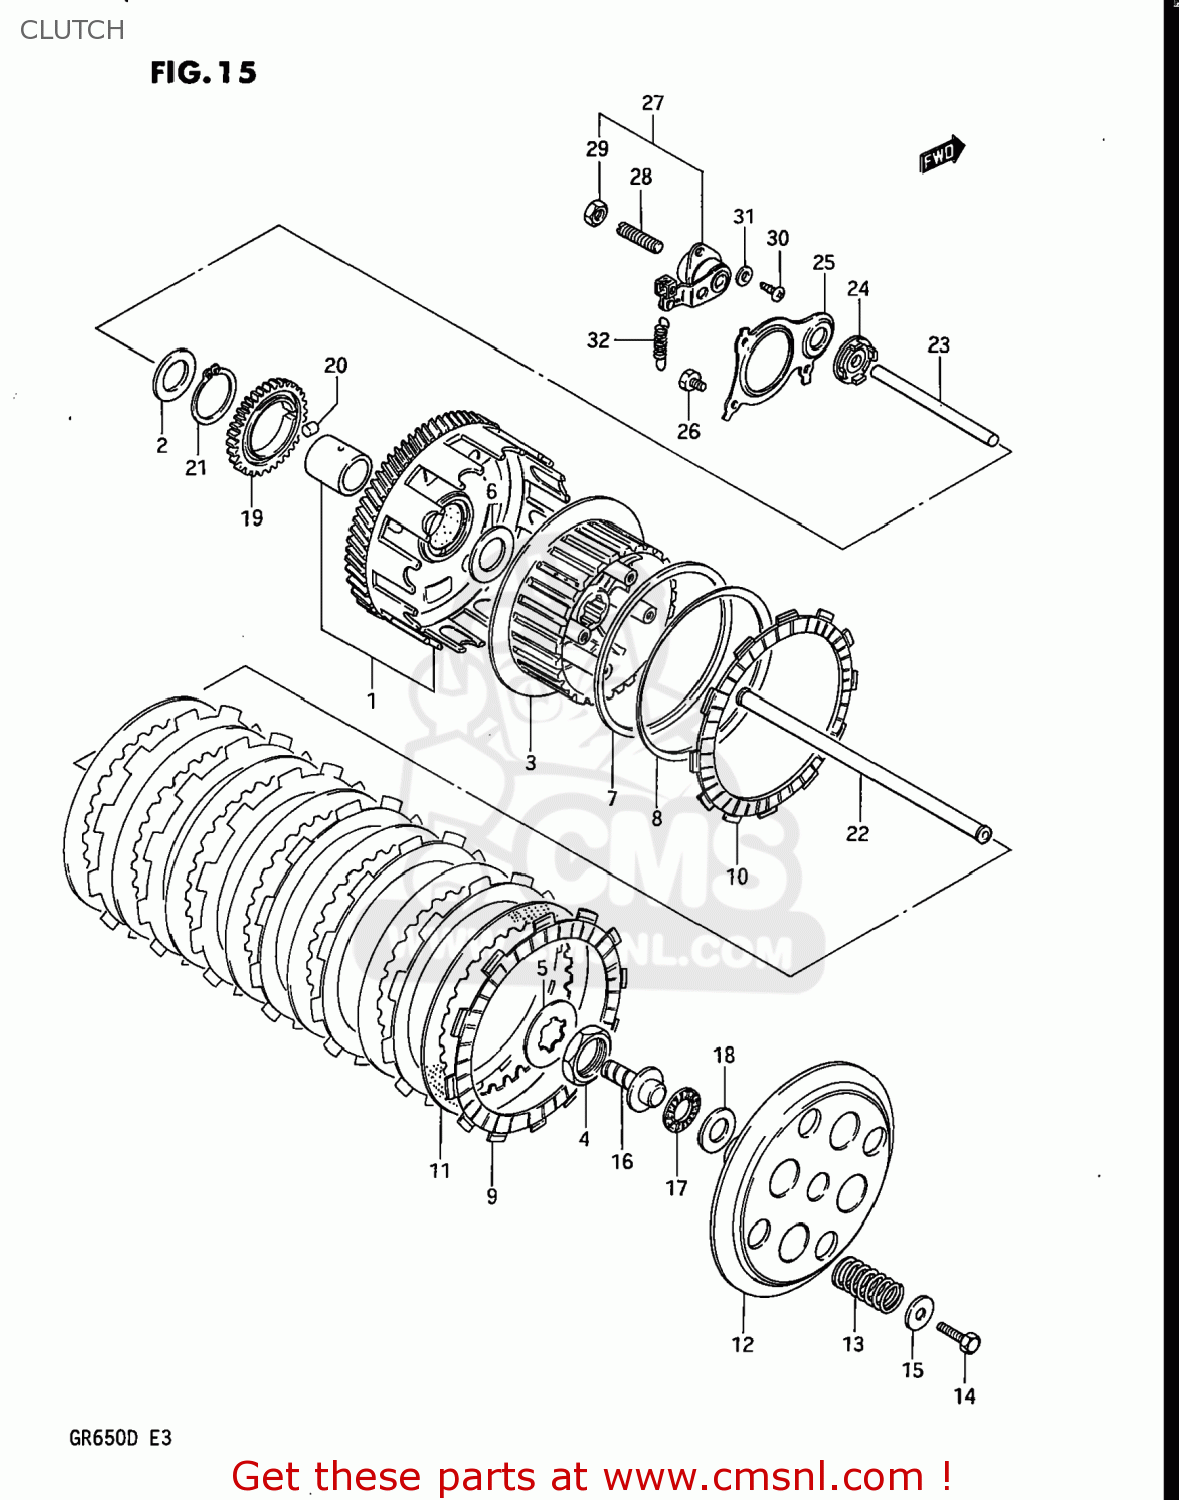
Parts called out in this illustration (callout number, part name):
1	GEAR ASSEMBLY,PRIMARY DRIVE
2	WASHER
3	HUB,CLUTCH SLEEVE
4	NUT
5	WASHER,LOCK
6	WASHER (22X40X1.5)
7	SEAT,WAVE WASHER(T:1.4)
8	WASHER
9	PLATE,CLUTCH DRIVE (NAS)
10	PLATE,CLUTCH DRIVE
11	PLATE,CLUTCH DRIVEN
12	DISC,CLUTCH PRESSURE
13	SPRING
14	BOLT, UPPER
15	WASHER
16	PIECE,CLUTCH PUSH
17	BEARING(15X28X2)
18	WASHER
19	GEAR,OIL PUMP DRIVE
20	PIN(6X6)
21	CIRCLIP
22	ROD,CLUTCH PUSH
23	ROD,CLUTCH PUSH,L
24	SEAL,OIL(6X34X10)
25	PLATE,CLUTCH PUSH ROD
26	BOLT
27	SCREW ASSEMBLY,RELEASE
28	SCREW
29	NUT 6MM
30	SCREW
31	WASHER
32	SPRING
